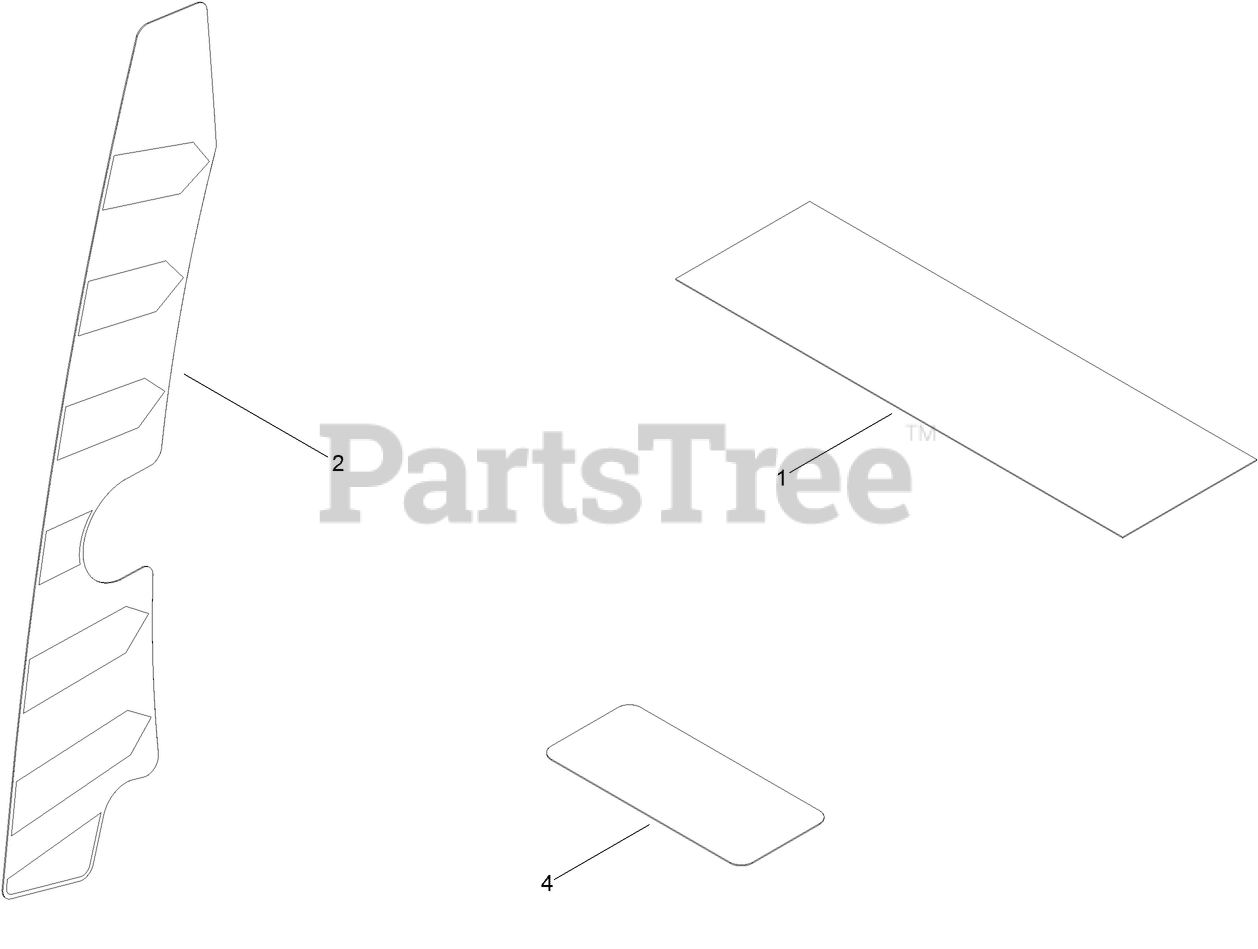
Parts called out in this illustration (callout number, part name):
1	DECAL-SERVICE, CE
2	DECAL-HOC
4	DECAL-LOCATION, SERVICE DEALER
